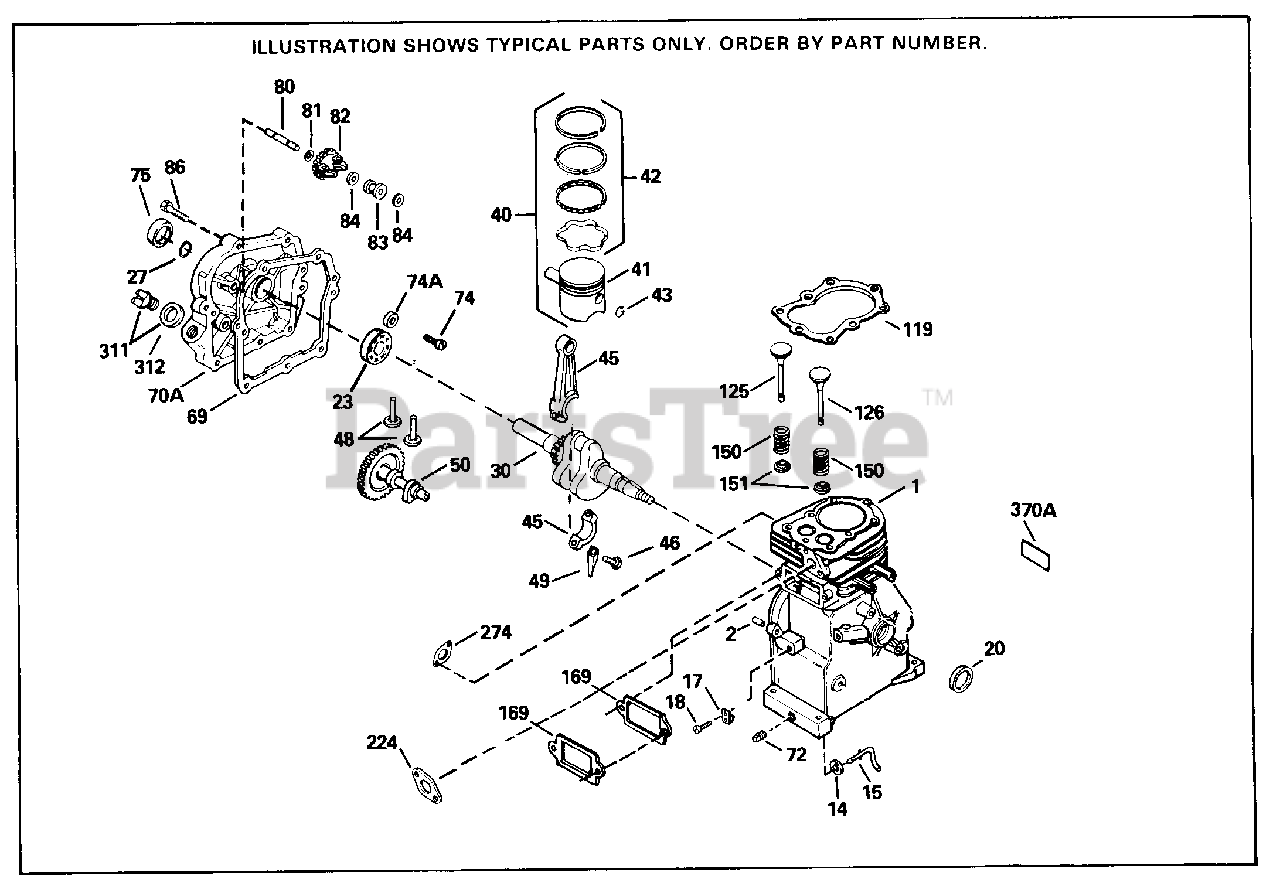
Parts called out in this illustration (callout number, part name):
1	"Cylinder (Incl. 2, 30 & 72) 2-1/2" Bo re
2	Dowel Pin
14	Flat Washer
15	Rod, Governor
17	Clamp, Governor lever
18	Screw, 8-32 x 5/16"
20	Seal, Oil
23	Ball Bearing
27	Bearing Retainer
30	Crankshaft
40	Piston, Pin & Ring Set (Std.)
40	Piston, Pin & Ring Set (.010" OS)
40	Piston, Pin & Ring Set (.020" OS)
41	Piston & Pin Ass'y. (Std.) (Incl. 43)
41	Piston & Pin Ass'y. (.010" OS) Incl. 43
41	Piston & Pin Ass'y. (.020" OS) Incl. 43
42	Ring Set (Std.)
42	Ring Set (.010" OS)
42	Ring Set (.020" OS)
43	Piston Pin Retaining Ring
45	Rod Assy., Connecting (Incl. 46 & 49)
46	Bolt, Connecting rod
48	Valve Lifter
49	Dipper, Oil
50	Camshaft
69	Cylinder Cover Gasket
70A	Cover, Cylinder Incl. 75, 80, 311 &31 2
72	Oil Drain Plug (Sq. hd., 1/4-18)
74	Screw, 10-24 x 9/16"
75	Oil Seal
80	Shaft, Mechanical governor
81	Washer, Flat
82	Gear, Governor (Incl. 81)
83	Spool, Governor
84	Retaining Ring
86	Screw, 1/4-20 x 1-1/4"
119	Cylinder Head Gasket
125	Exhaust Valve (Std.) (Incl. 151)
125	Exhaust Valve (1/32" OS) (Incl. 151)
126	Intake Valve (Std.) (Incl. 151)
126	Exhaust Valve (1/32" OS) (Incl. 151)
150	Spring, Valve
151	Cap, Valve spring
169	Gasket, Breather
274	Gasket, Exhaust
311	Oil Fill Plug (Incl. 312) also availa ble in Packaged Part #740079
312	Oil Fill Plug Gasket
370A	Decal, Instruction
